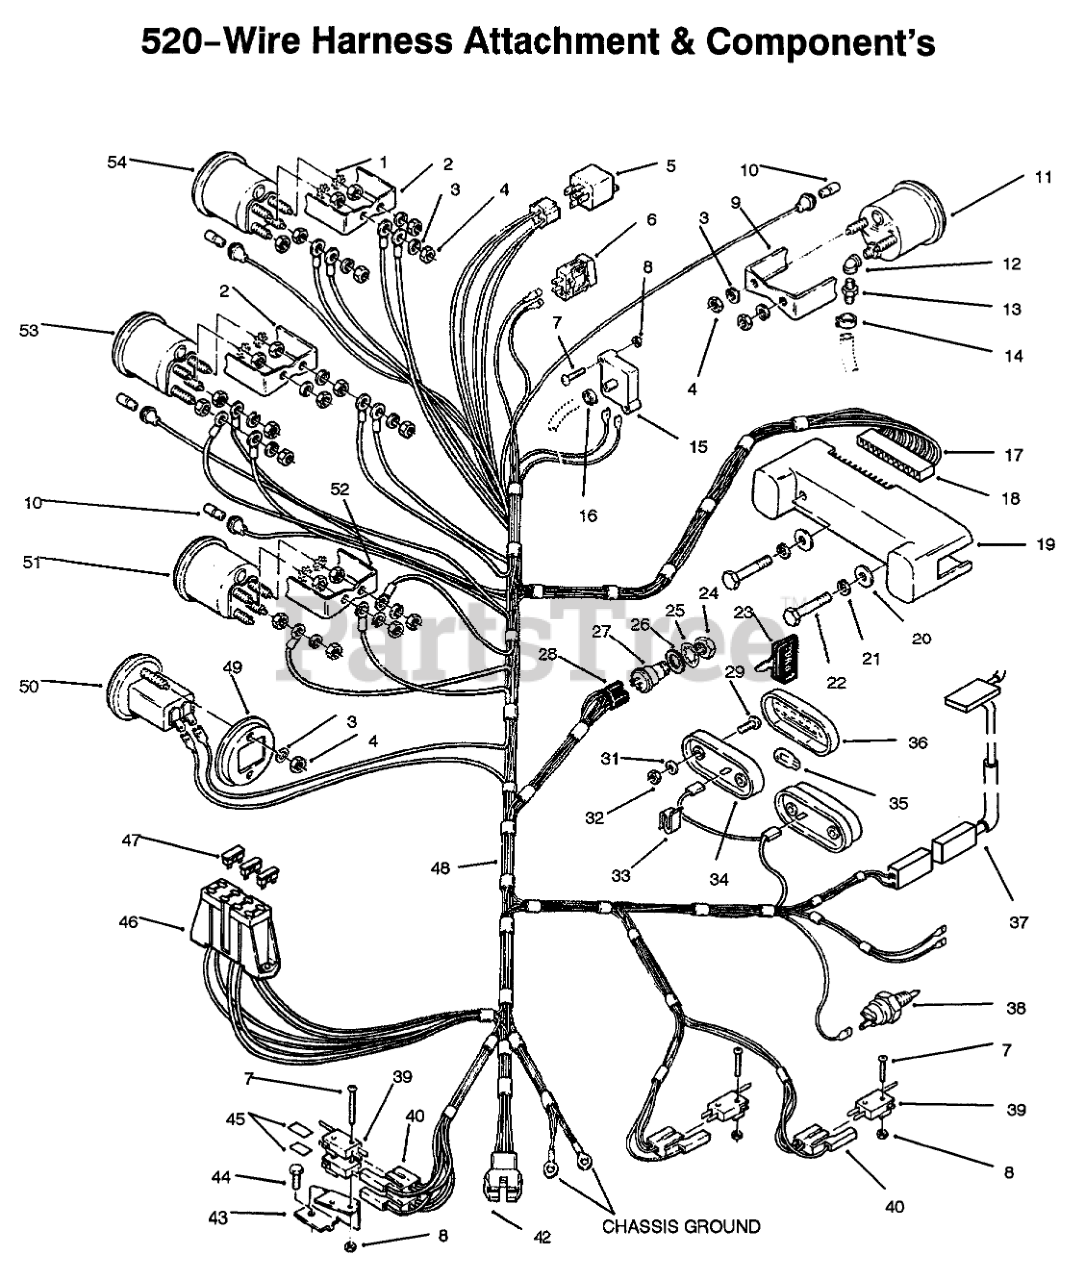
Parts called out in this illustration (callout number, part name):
1	WASHER-LOCK
2	CLAMP-MOUNTING
3	WASHER-LOCK
4	NUT-HEX
5	RELAY
6	SWITCH-HEADLIGHT
7	Screw
8	NUT HEX 4-40 ELAST
9	Bracket-Mounting
10	LAMP-MINIATURE GE 53X
11	Gauge-Vacuum (Incl. Ref. #3-4 & 9)
12	ELBOW
13	FITTING STRAIGHT
14	Clamp
15	ASSEMBLY - CHUTE W/DECAL
16	CLAMP-HOSE 5/16"
17	Terminal
18	Connector-Male
19	CIRCUIT-BRD 8 LIGHT
20	WASHER-FLAT
21	WASHER-LOCK
22	SCREW
23	KEY-IGNITION
25	WASHER-LOCK
26	Washer
27	Switch-Ignition (Incl. Ref. #24-26)
28	CONNECTOR-5 WAY-SERV
29	Screw
31	WASHER-LOCK, INT
32	NUT-HEX
33	SPEED CLIP
34	BASE-TAIL LIGHT
35	LIGHT BULB
36	LENS-TAIL LIGHT
37	SWITCH-SEAT
38	SENSOR-HYDRO OIL HOT
39	SWITCH
40	CONNECTOR BODY
42	9-CIRCUIT CAP
43	Support-Switch
44	Bolt
45	BARRIER - SWITCH
46	FUSE-HOLDER 4 WAY
47	FUSE-BLADE, 10 AMP
48	WIRING-HARNESS & DIA
49	Bracket-Mountin
50	Hourmeter (Incl. Ref. #3-4 & 49)
51	Tachometer (Incl. Ref. #1, 3-4 & 5 52)
52	MOUNTING-BRACKET
53	Gauge-Fuel (Incl. Ref. #1-4)
54	Voltmeter (Incl. Ref. #1-4)
